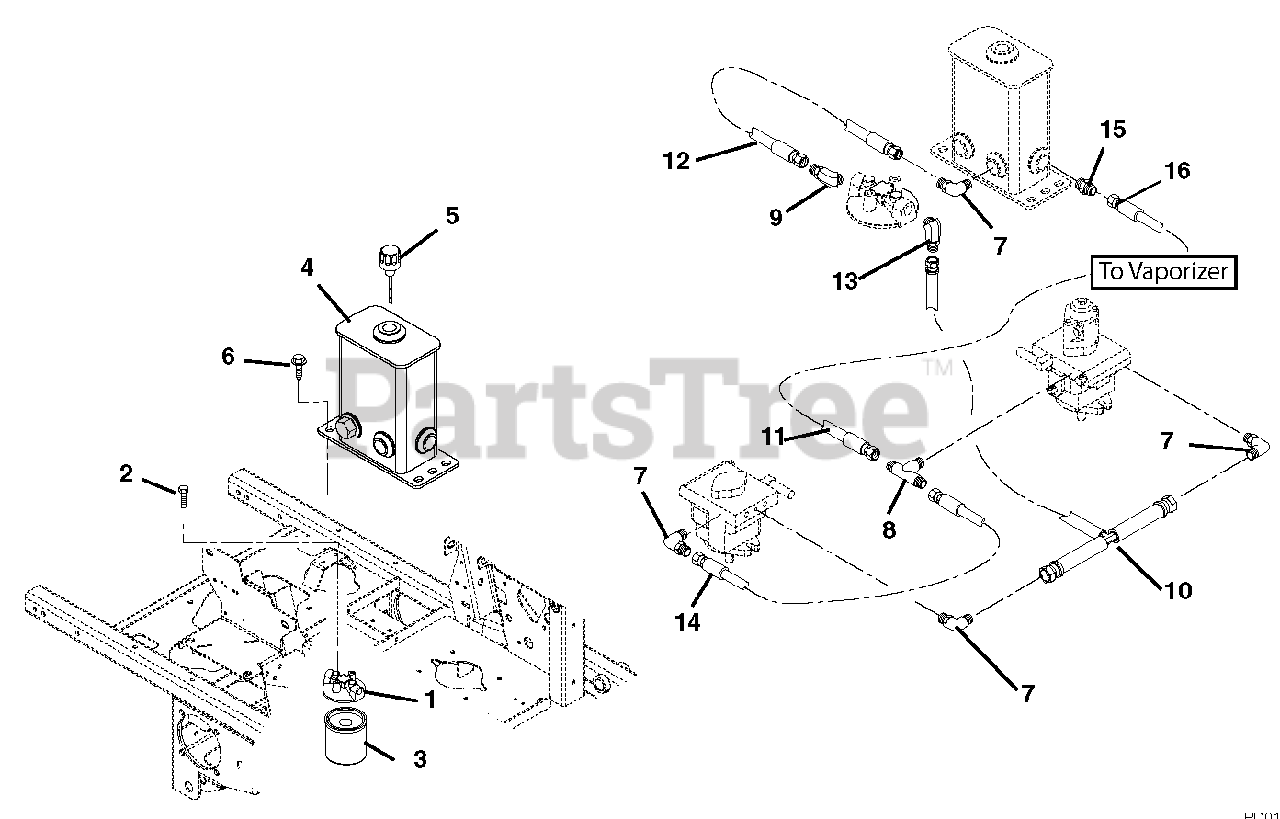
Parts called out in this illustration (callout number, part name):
1	Head, Filter
2	Bolt, Hex .25-20 x .50 Grade 5 Epoxy
3	Oil Filter
4	Weldment,Formed Hydraulic Tank-2 PORT
5	Hydraulic Tank Dipstick
6	Screw, Tapping .38-16 x .75 Hex Washer Head
7	Fitting, Hydraulic, 90 Degree Elbow, Steel M8F-M80
8	Fitting, Hydraulic Tee M80-M80-M80
9	Fitting, Hydraulic Straight M80-M80
10	Hose, Tee Assembly, .50
11	Hose, Hydraulic .50-31 F8F0-F8F0
12	Hose, Hydraulic Molded
13	Fitting, Hydraulic 45 Degree
14	Hose, Hydraulic
15	Fitting, Hydraulic 45 Degree M8F-M80
16	Hose, Hydraulic .50-13-OK F8F0-F8F0
